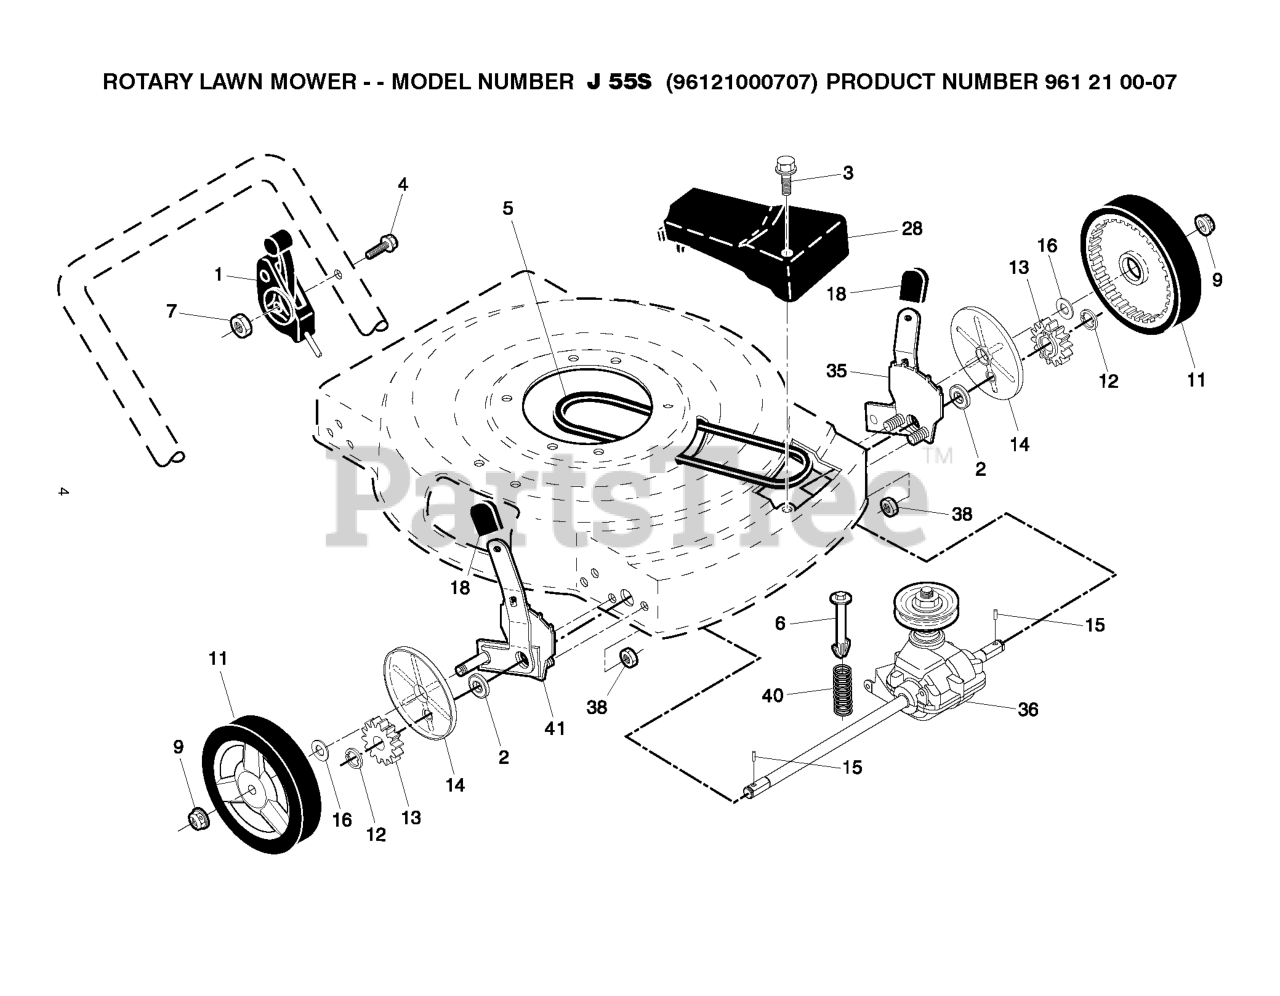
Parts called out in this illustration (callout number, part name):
1	DRIVE CONTROL 59.8 FWGD
2	BEARING.ASM.
3	SCREW, HEX HD TAPPING #10-24 1
4	SCREW.PAN.HEAD
5	BELT THERM .32
6	SPRING RETAINER
7	NUT.HEX.FLANGE.1/4
9	NUT.HEX.FLANGE.3/8-16.LO(3 2)
11	WHEEL.8X1.75.H3SPK.RAD3.GY.BU3
12	E-RING 7/16 RE
13	PINION.14.TEETH.FGD
14	COVER.DUST.WHEEL
15	PAWL, DRIVE
16	WASHER FLUT
18	SELECTOR KNOB
35	KIT ADJUSTER ASM.438151.
36	TRANSMISSION.22.FGD/W/PULLEY
38	LOCKNUT.NYLOC.1/4-20
40	SPRING.EXTENSION
41	KIT ADJUSTER ASM.438148
